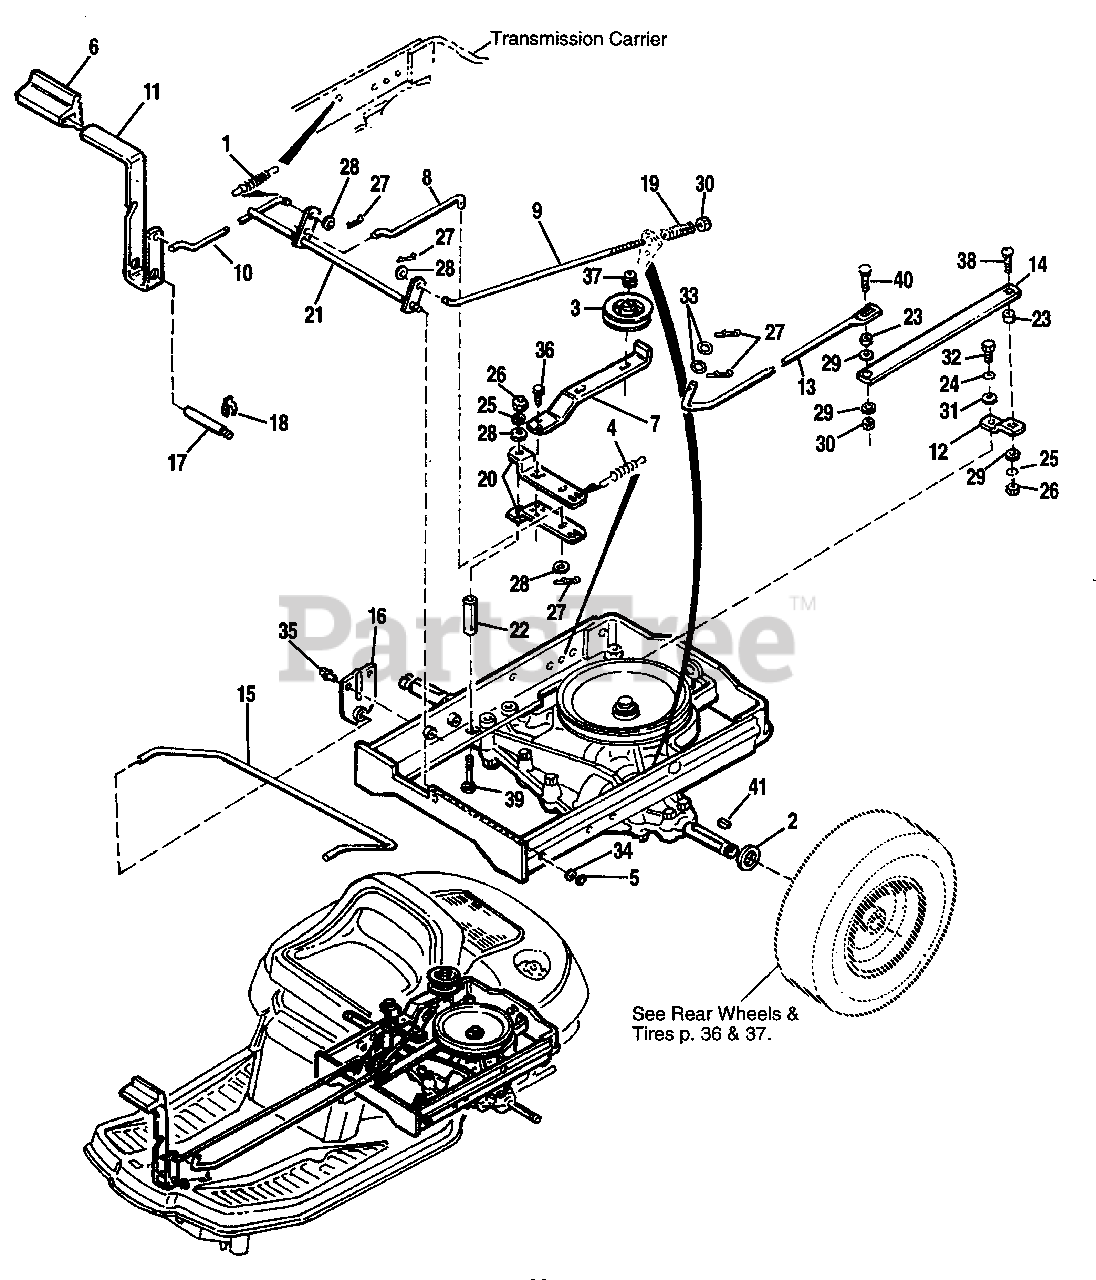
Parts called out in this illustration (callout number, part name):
1	SPRING, Return
2	WASHER, 3/4
3	PULLEY, Idler
4	SPRING, Idler
5	KLIPRING, 1/2
6	PAD, Pedal
7	LEVER, Idler, Pulley
8	ROD, Clutch, Rear
10	ROD, Clutch, Front
11	LEVER, Clutch
12	BRACKET, Shift
13	ROD, Shift, Front
14	BAR, Shift, Rear
15	TORSION BAR
16	BRACKET, Torsion Bar
17	PIVOT, Brake
18	KLIP RING, 3/8
19	SPRING, Compression
20	CLEVIS, Idler, Bracket
21	PIVOT SHAFT ASSY.
22	SPACER, Pivot
24	LOCKWASHER, 1/4
25	LOCKWASHER, 5/16
26	NUT, Hex, 5/16-18
27	COTTER PIN, 3/32 x 3/4
28	WASHER, Plain
29	WASHER, Plain, 5/16
30	NUT, Hex, Nylon Lock, 5/16-18
31	WASHER, Plain, 17/64 x 5/8 x 3/64
32	SCREW, Hex Hd., 1/4-28 x 5/8
34	WASHER, Plain, 1/2
35	SCREW, Hex Hd., Flange, Taptite, 5/16-18 x 1/2
36	SCREW, Hex Hd., Flange, Taptite, 1/4-20 x 5/8
37	NUT, Hex, Flange Lock, 3/8-16
38	CARRIAGE BOLT, 5/16-18 x 1
39	CARRIAGE BOLT, 5/16-18 x 2-3/4
40	CARRIAGE BOLT, 5/16-18 x 1-1/4
41	KEY
